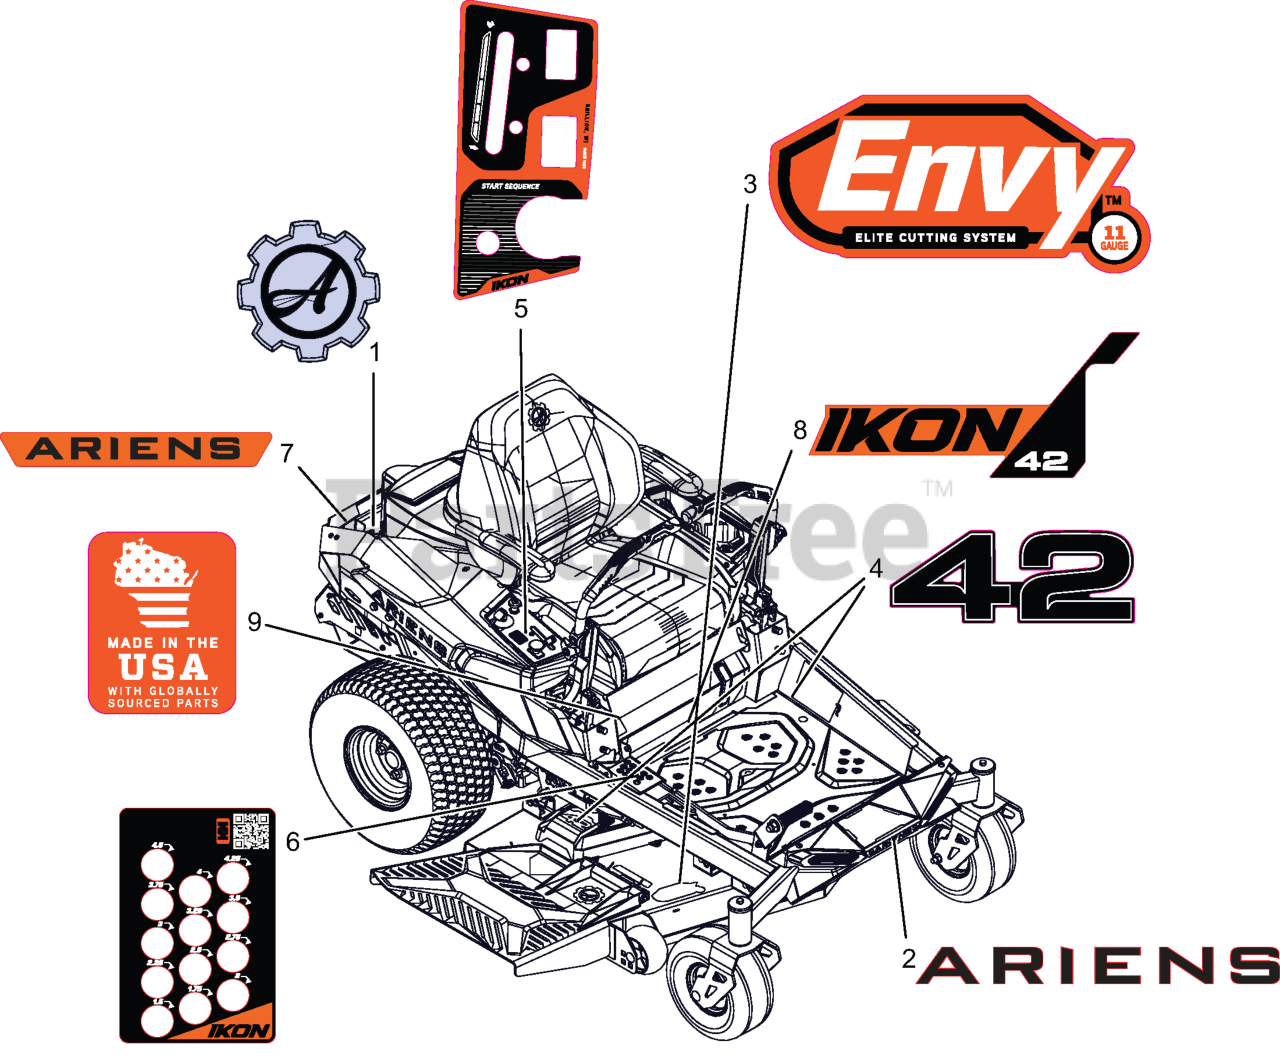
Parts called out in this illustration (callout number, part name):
1	DECAL- ARIENS GEAR BADGE
2	DECAL- ARIENS-BADGE
3	DECAL- DECK
4	DECAL- 42
5	DECAL- CONTROL PANEL
6	DECAL- HEIGHT OF CUT
7	DECAL- ARIENS
8	DECAL- IKON 42 KICKPLATE
9	DECAL- MADE IN USA
